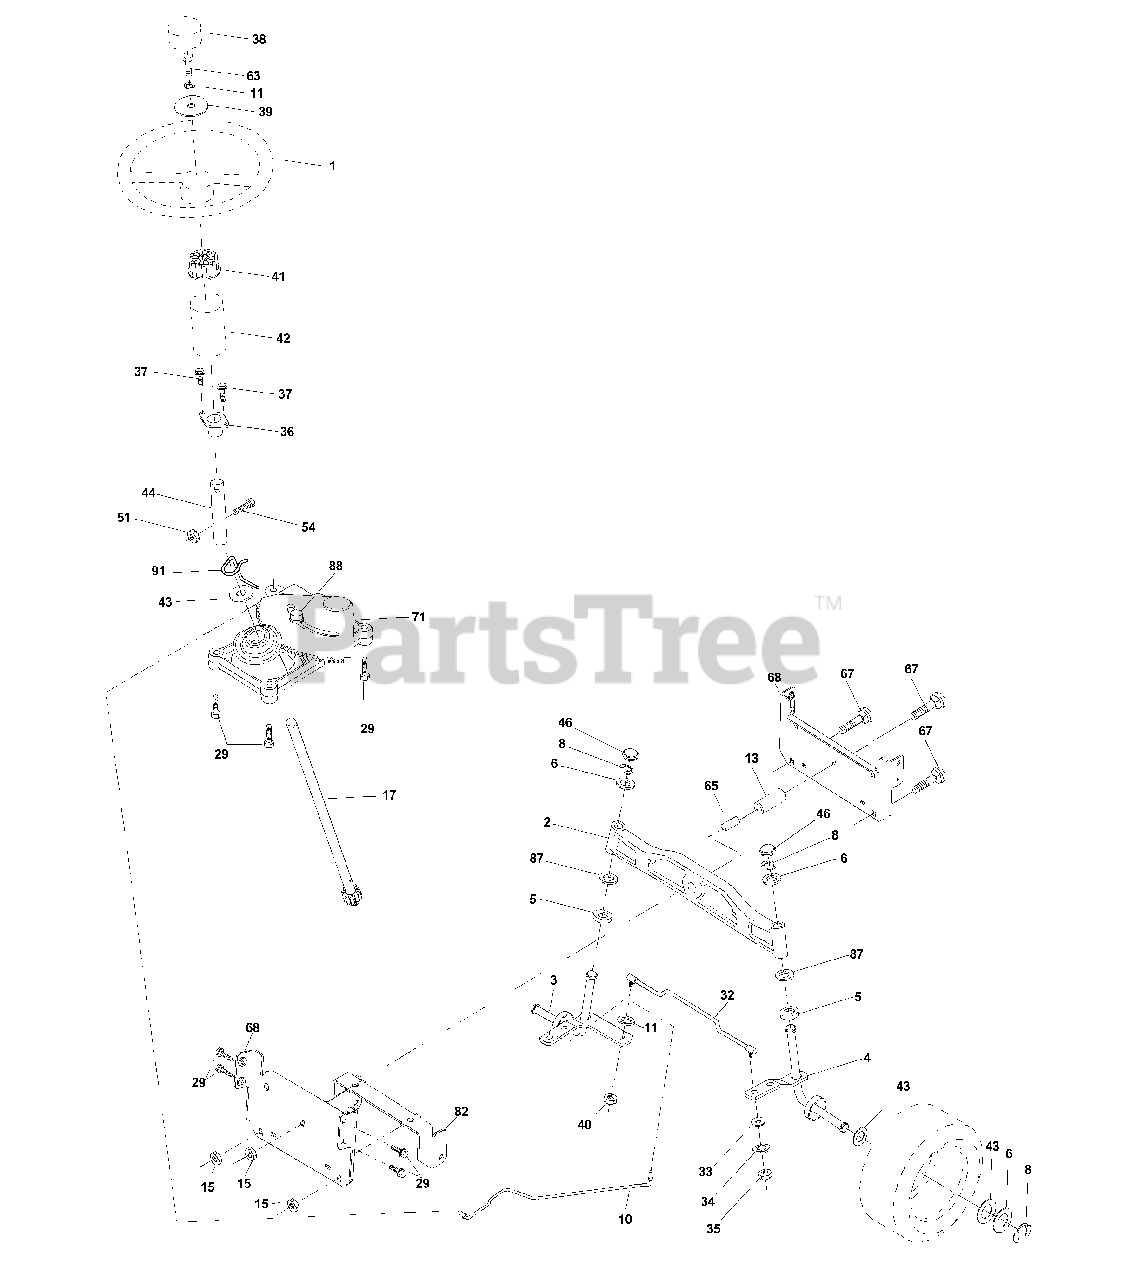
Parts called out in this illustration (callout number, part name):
1	Wheel Steering
2	Axle Asm Cast Iron LT
3	Spindle Asm LH
4	Spindle Asm RH
5	Bearing Race Thrust Harden
6	Washer 25/32 X 1-5/8 X 16 Ga
8	Ring Klip #t5304-75
10	Link Drag
11	Washer Lock Hvy Hlcl Spr 3/8
13	Spacer Brg. Axle Front
15	Nut Hex Flange Lock
17	Shaft Asm. Steering
29	Screw 3/8-16x.75
32	Rod Tie
33	Washer 11/32 x 3/4 x 16 Ga.
34	Washer Lock Hvy Hlcl Spr 5/16
35	Crownlock Nut 5/16-24
36	Bushing Strg
37	Screw
38	Insert Cap Strg Wh Au
39	Washer 13/32 X 2-3/8 X 12 Ga
40	Lock nut
41	Adaptor Wheel Strg
42	Boot Steering Dash
43	Washer 25/32 X 1 1/4 X 16 Ga
44	Extension Steering Shaft LR/LT
46	Cap Spindle Fr Top Blk
51	Nut Lock Hex w/Ins 5/16-18
54	Bolt Fin Hex 5/16-18 Unc x 1-1/4
63	Bolt Fin Hex 3/8-16unc x 1 Gr. 5
65	Brace Axle
67	Bolt Rdhd Sq 3/8-16 Unc x 2-1/4
68	Axle, Brace
71	Steering Asm.
82	Bracket Susp. Chassis Front
87	Washer Flat .781 x 1-1/2 x .14
88	Bolt Shoulder 7/16-20 Unc
91	Clip Steering
